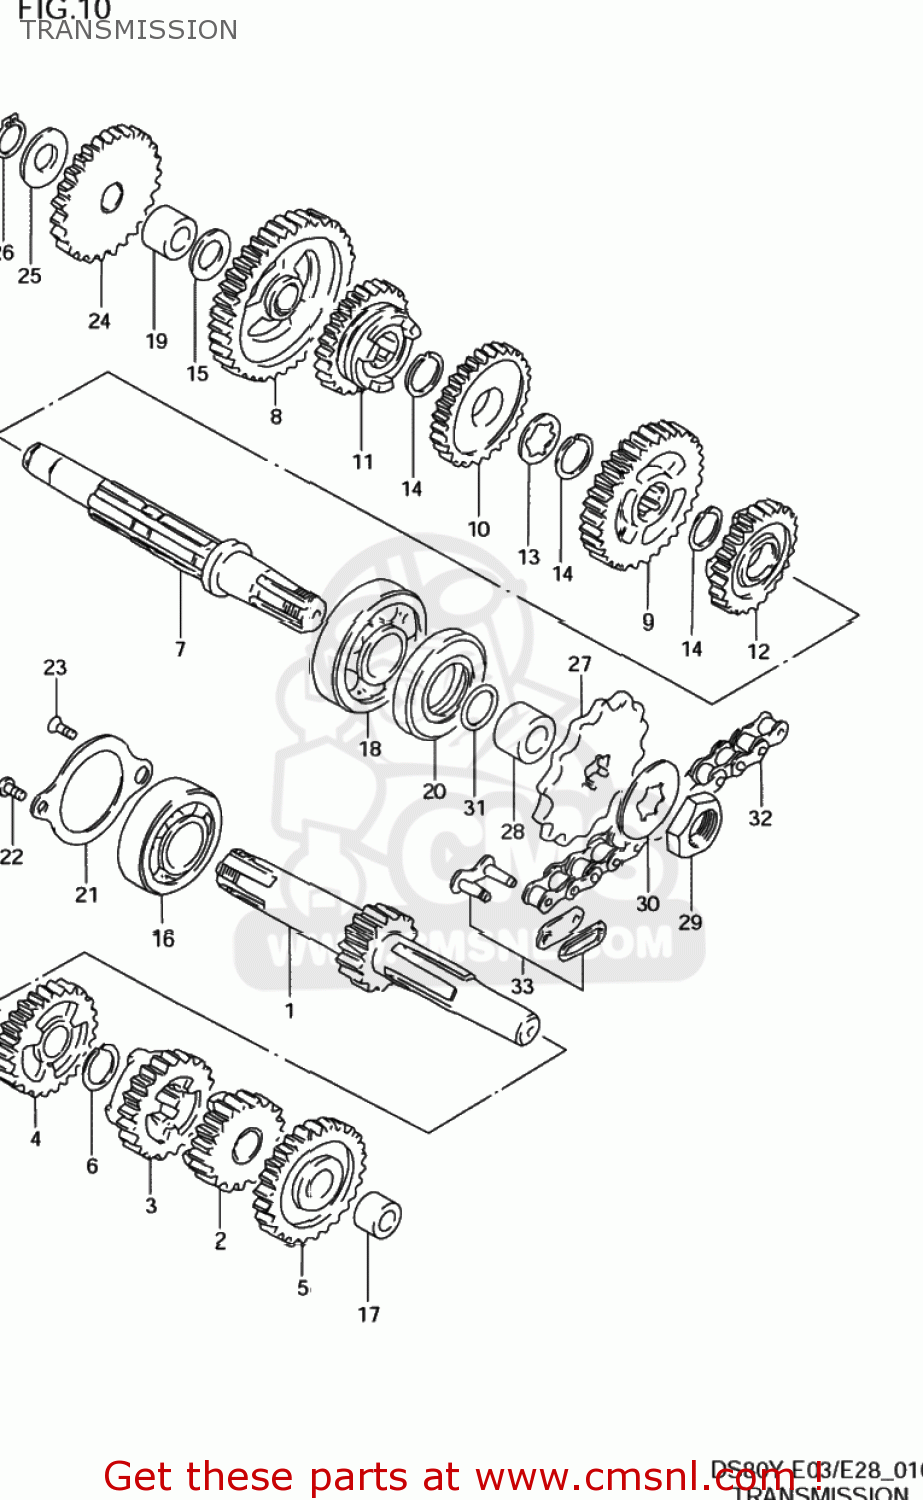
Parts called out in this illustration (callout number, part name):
1	SHAFT,COUNTER(NT:13)
2	GEAR,2ND DRIVE(NT:19)
3	GEAR,3RD DRIVE(NT:22)
4	GEAR,4TH DRIVE(NT:24)
5	GEAR,FIFTH DRIVE
6	CIRCLIP
7	SHAFT,DRIVE
8	GEAR,1ST DRIVEN(NT:35)
9	GEAR,2ND DRIVEN(NT:32)
10	GEAR,3RD DRIVEN(NT:29)
11	GEAR,4TH DRIVEN(NT:36)
12	GEAR,5TH DRIVEN(NT:24)
13	WASHER,LOCK
14	CIRCLIP
15	WASHER(13X24X1)
16	BEARING(17X40X12)
17	BUSH
18	BEARING
19	BUSH
20	SEAL,OIL(21X40X6)
21	RETAINER,CNTR SHAFT BEARING
22	SCREW
23	SCREW
24	GEAR,KICK STARTER IDLE
25	WASHER
26	CIRCLIP,12 MM
27	SPROCKET,ENGINE
28	SPACER(17X21X13)
29	NUT
30	WASHER,LOCK
31	O RING(D:1,ID:16.8)
32	CHAIN,DRIVE
33	JOINT,CHAIN
